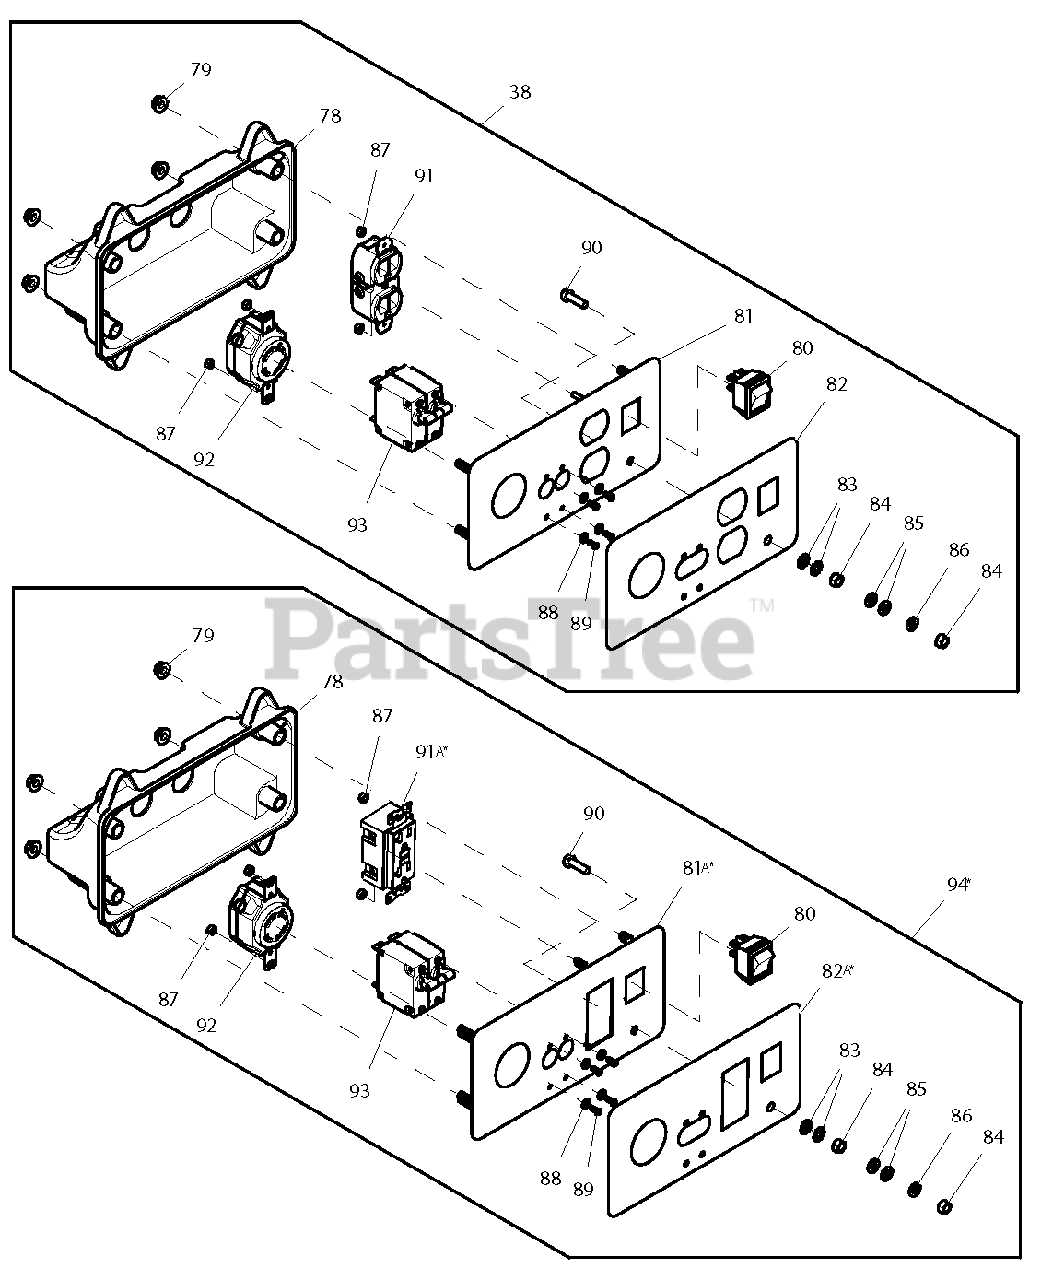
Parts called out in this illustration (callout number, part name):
38	ASSY CONTROL PNL H3250 49ST
78	CNTRL PNL BACK BOX HNYWL 3250
79	NUT HEX M6-1.0 G8 CLEAR ZINC
80	SW RUN-STOP HONEYWELL
81	WELDMENT FACEPLATE H3250 49ST
81A	WELDMENT FACEPLATE H3250 CARB
82	OVERLAY CNTRL PNL HW 3250 49ST
82A	OVERLAY CNTRL PNL HW 3250 CARB
83	WASHER LOCK EXT 1/4 BLACK ZINC
84	NUT HEX M6-1.0 G8 BLACK ZINC
85	WASHER FLAT M6 BLACK ZINC
86	WASHER LOCK M6 BLACK ZINC
87	NUT HEX M4-0.7 G8 YEL CHR
88	WASHER FLAT M3 BLACK ZINC
89	SCREW PPHM M3-0.5 X 6 BLACK ZN
90	SCREW HHC M6-1.0X20 C8.8 BLKZN
91	OUTLET 20A 120V DPLX SPECGRADE
91A	OUTLET 20A 120V GFCI GF20BK
92	OUTLET 20A 120/250V SPCGR
93	CB 0014A 2P 250V
94	ASSY CONTROL PNL H3250 CARB
